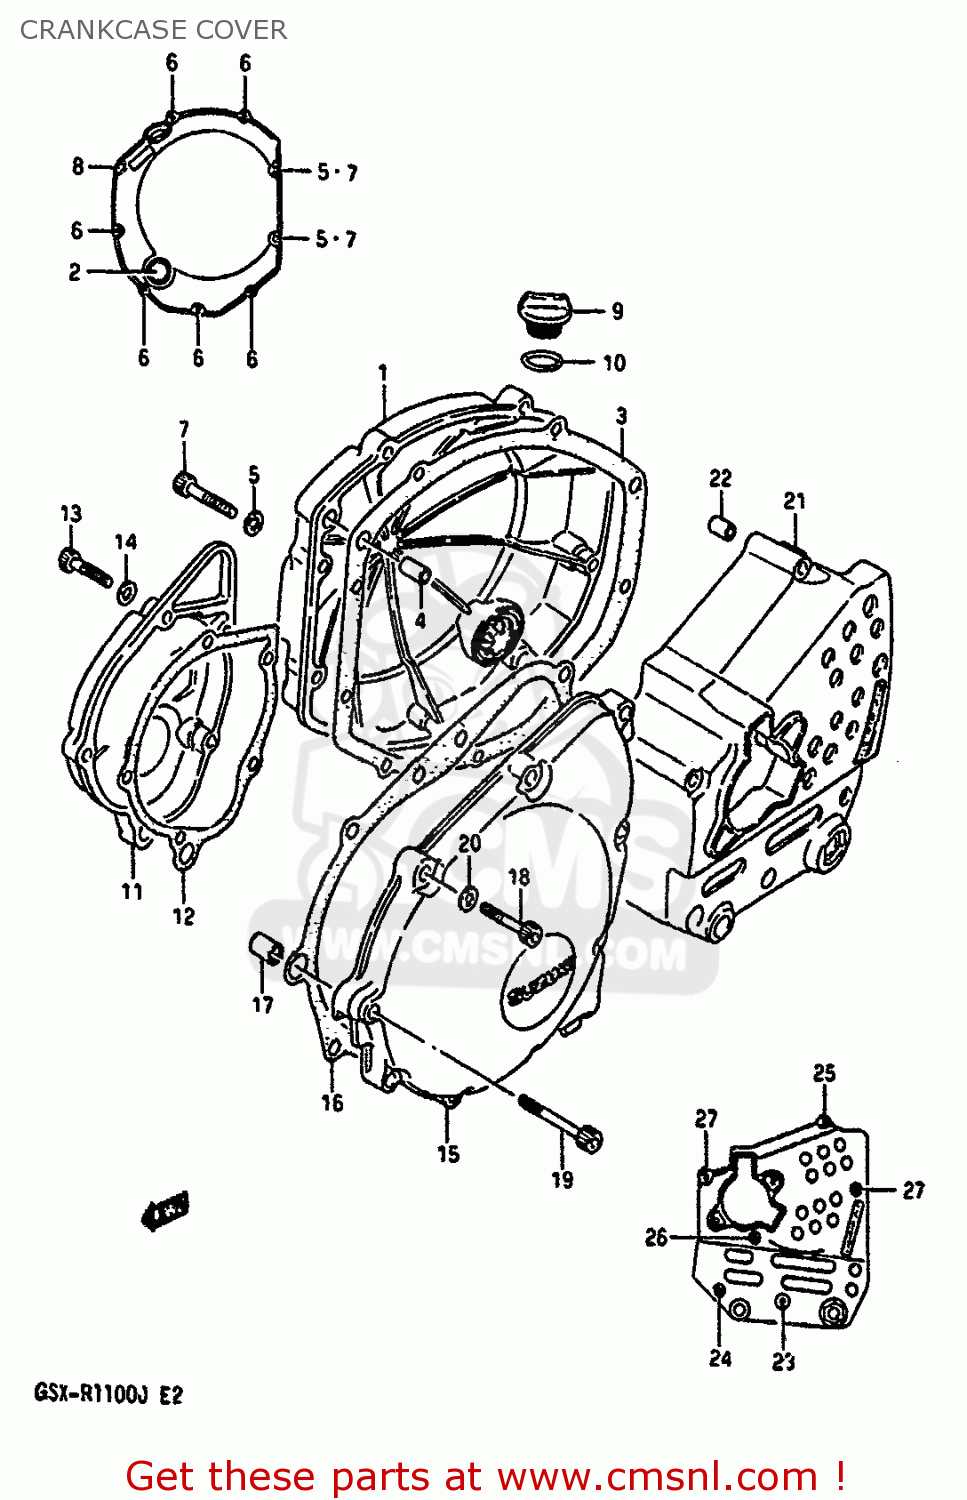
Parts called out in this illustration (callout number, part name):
1	COVER COMP,CLUTCH
2	LENS,OIL LEVEL CHECK
3	GASKET,CLUTCH COVER (MCA)
4	PIN
5	GASKET(5.8X11X1.2) (NAS)
6	BOLT
7	BOLT
8	BOLT
9	PLUG
10	O RING(D:3.1,ID:16.8)
11	COVER,SIGNAL GENERATOR
12	GASKET,SIGNAL GENERATOR COVER (NAS)
13	BOLT
14	GASKET(5.8X11X1.2) (NAS)
15	COVER,STARTER GEAR
16	GASKET,STARTER GEAR COVER (MCA)
17	PIN (11X20)(SUS)
18	BOLT
19	BOLT
20	GASKET(5.8X11X1.2) (NAS)
21	COVER,ENGINE SPROCKET
22	PIN
23	BOLT
24	BOLT
25	BOLT
26	BOLT
27	BOLT
